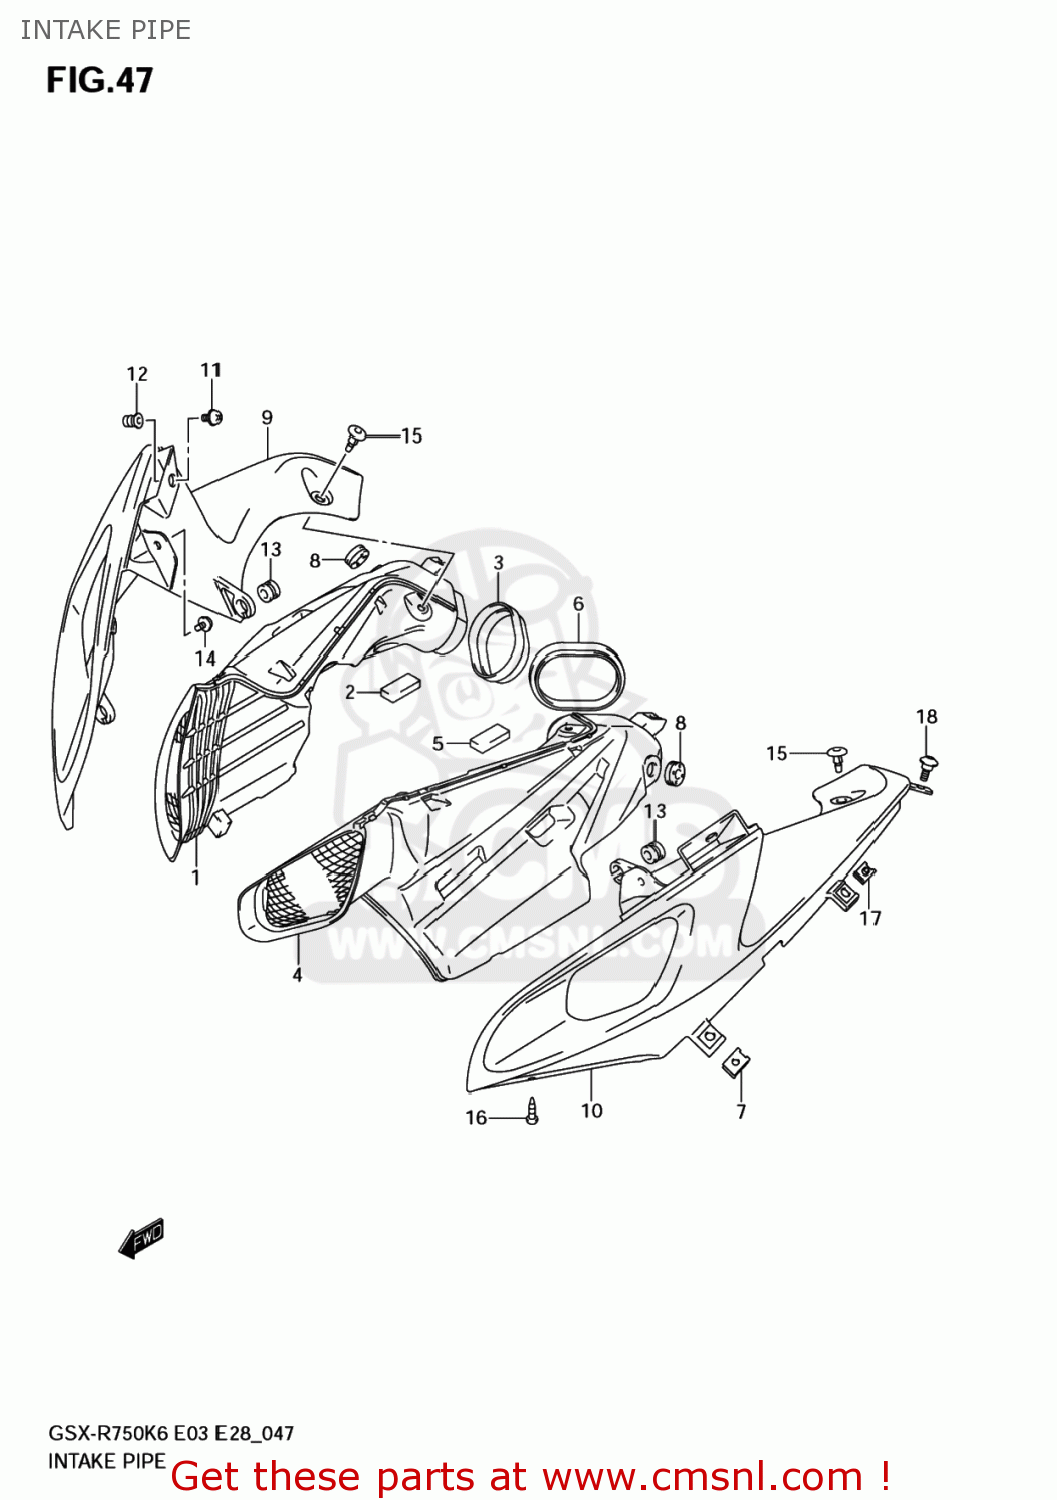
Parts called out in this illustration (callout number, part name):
1	PIPE,AIR INTAKE,R
2	CUSHION,INTAKE PIPE
3	MOLDING,AIR INTAKE,R
4	PIPE,AIR INTAKE,L
5	CUSHION,INTAKE PIPE
6	MOLDING,AIR INTAKE,L
7	NUT,COWL
8	CUSHION
9	COVER,INTAKE,R(BLACK)
10	COVER,INTAKE,L(BLACK)
11	SCREW
12	NUT
13	CUSHION
14	SCREW(5X15)
15	CLIP
16	SCREW
17	NUT,COWL
18	SCREW(5X16)
